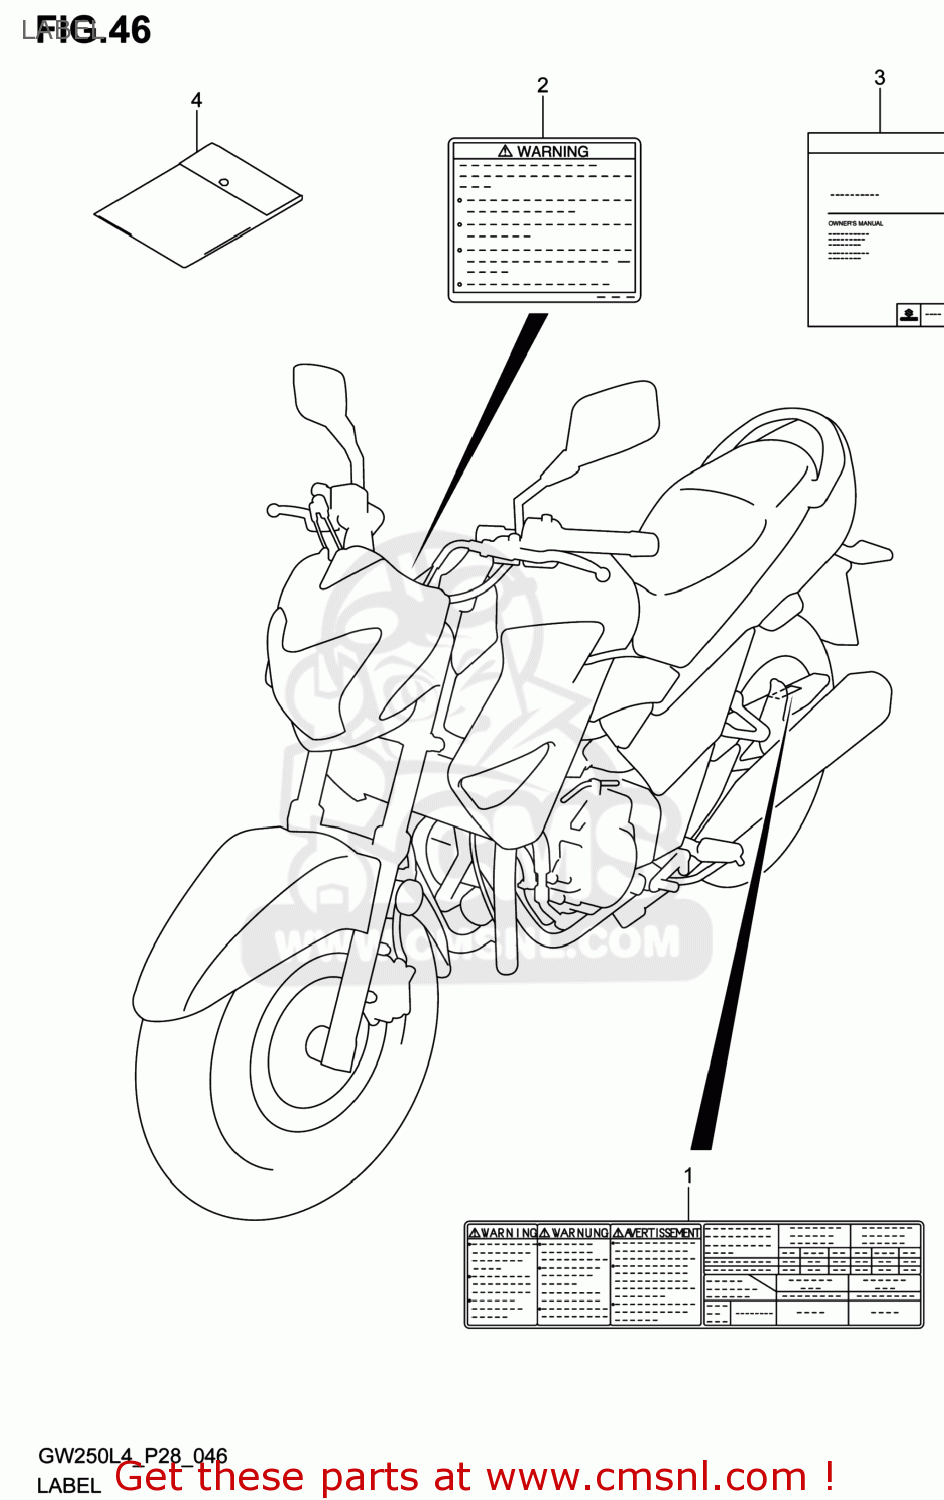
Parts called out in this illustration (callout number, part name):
1	LABEL,TIRE INFORMATION
2	LABEL,GENERAL WARNING
3	MANUAL,OWNER'S
4	BAG,OWNER'S MANUAL
